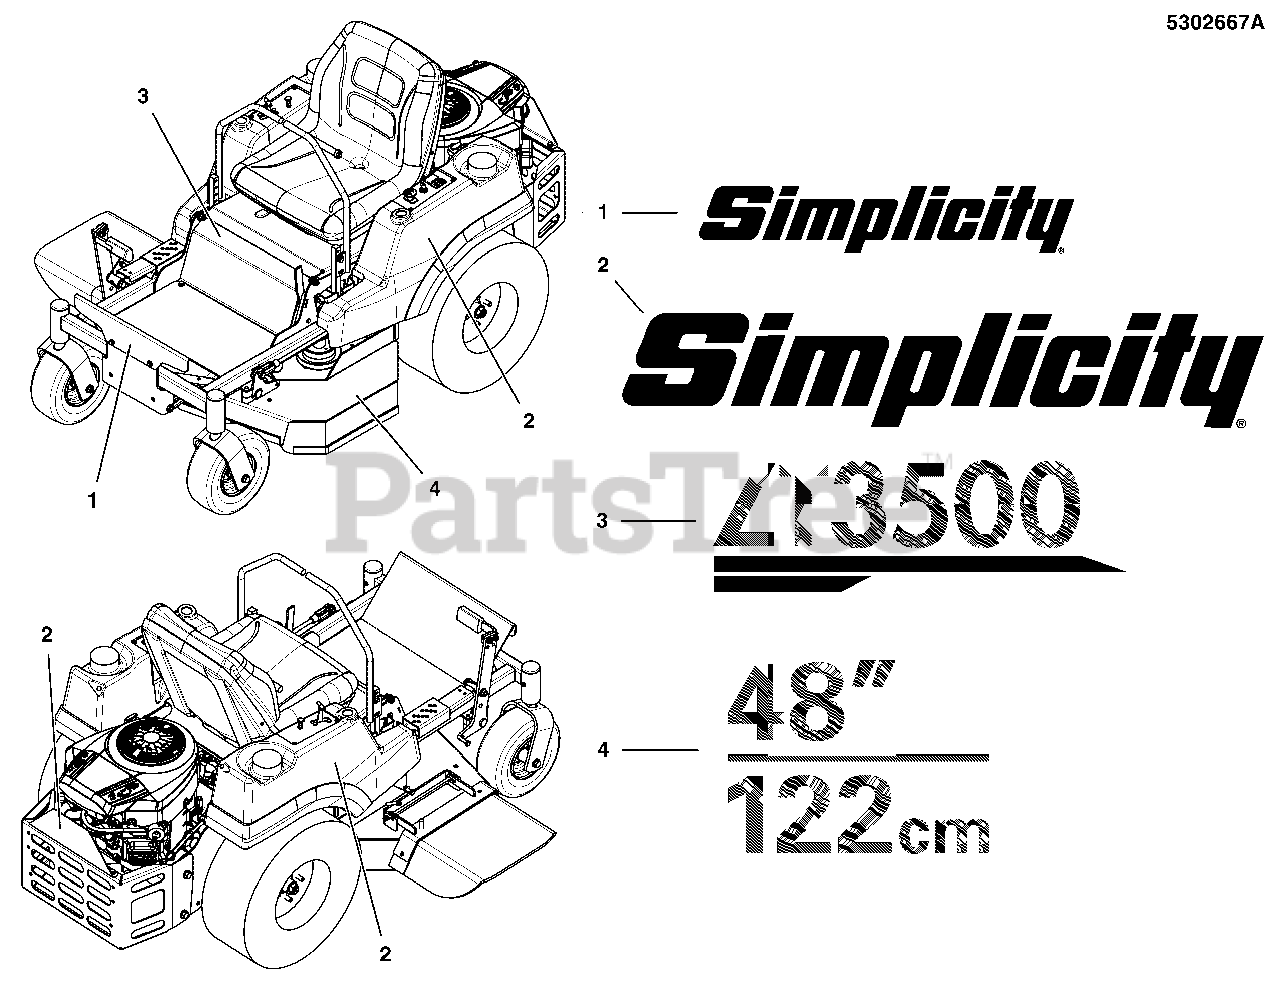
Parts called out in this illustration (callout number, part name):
1	DECAL, SMI LOGO 6.20"
2	DECAL, SMI LOGO 10.47"
3	DECAL, LOGO, ZT3500
4	DECAL, MOWER WIDTH 48IN/122CM
